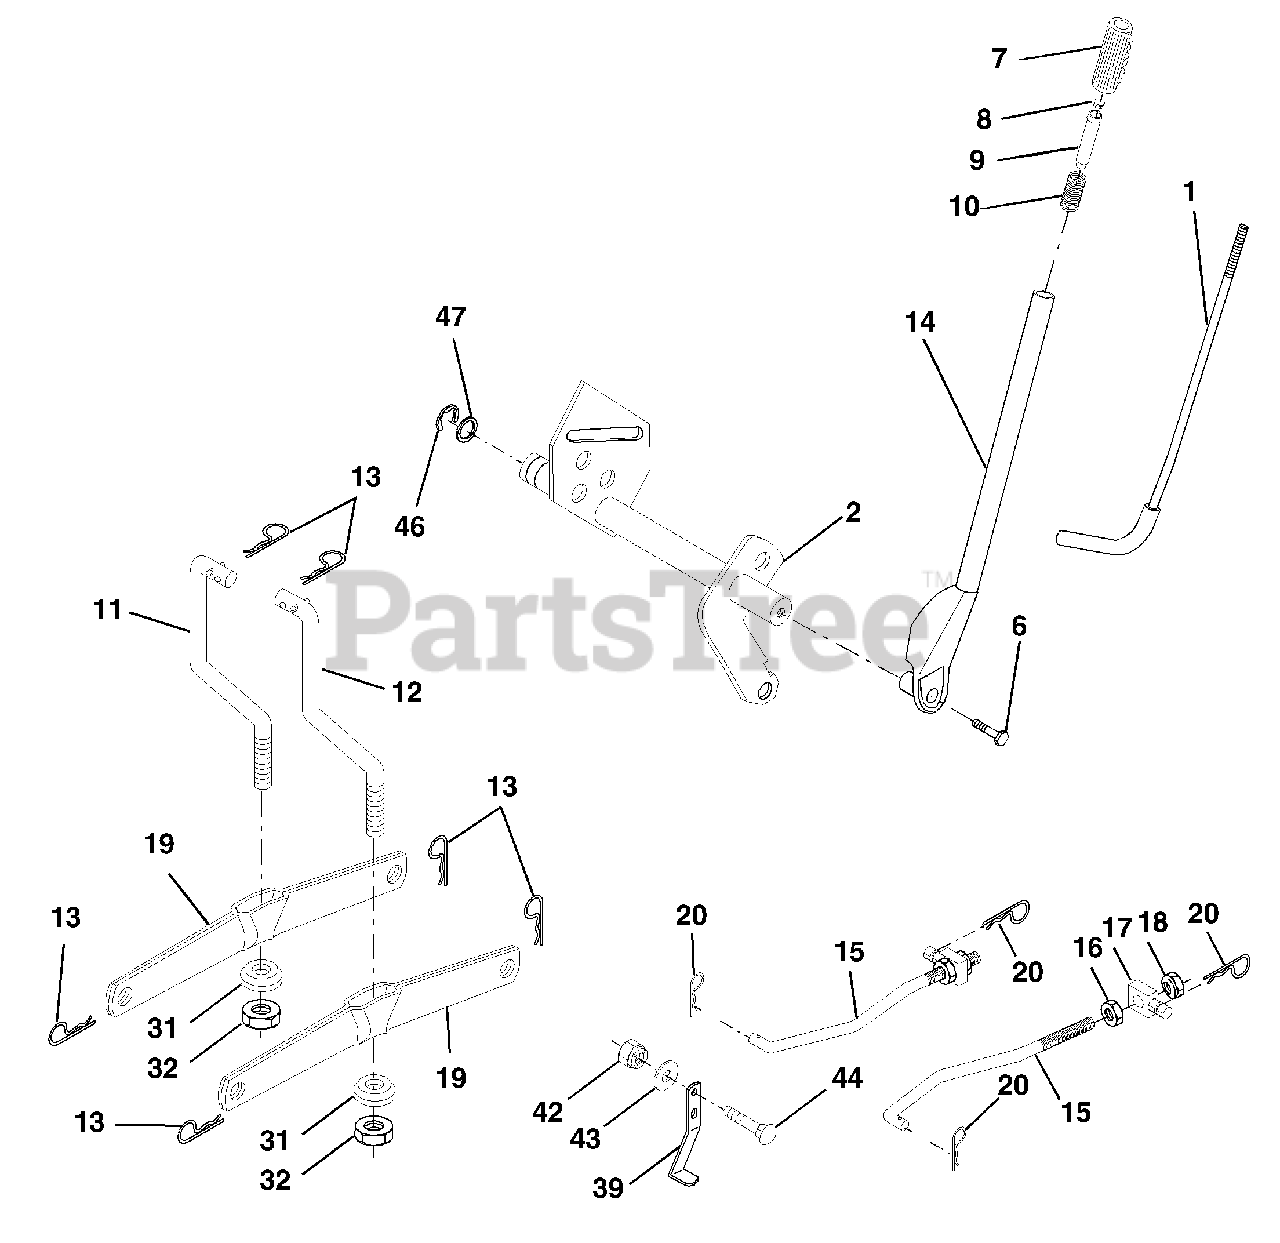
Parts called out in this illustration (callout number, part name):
1	Rod Assembly, Lever
2	Shaft Assembly, Lift
6	Bolt, Hex Head, Fin. 3/8-16 x 1-1/2
7	Grip Handle
8	Button Plunger Black
9	Plunger Lever Lift
10	Spring
11	Link, Lift, LH
12	Link, Lift, RH
13	Retainer Spring
14	Lever Assembly, Lift, RH
15	Link, Front
16	Nut, Hex, Jam 1/2-13 UNC
17	Trunnion
18	Nut Lock W/Wsh 1/2-13 Unc
19	Arm, Suspension, Rear
20	Retainer Spring
31	Bearing
32	Nut, Crownlock 3/8-24
39	Stop Over Center
42	Nut, Crownlock 3/8-16 UNC
43	Washer 13/32 x 1 x 12 Ga.
44	Bolt, Carriage 3/8-16 x 1.00
46	E-Ring
47	Washer
